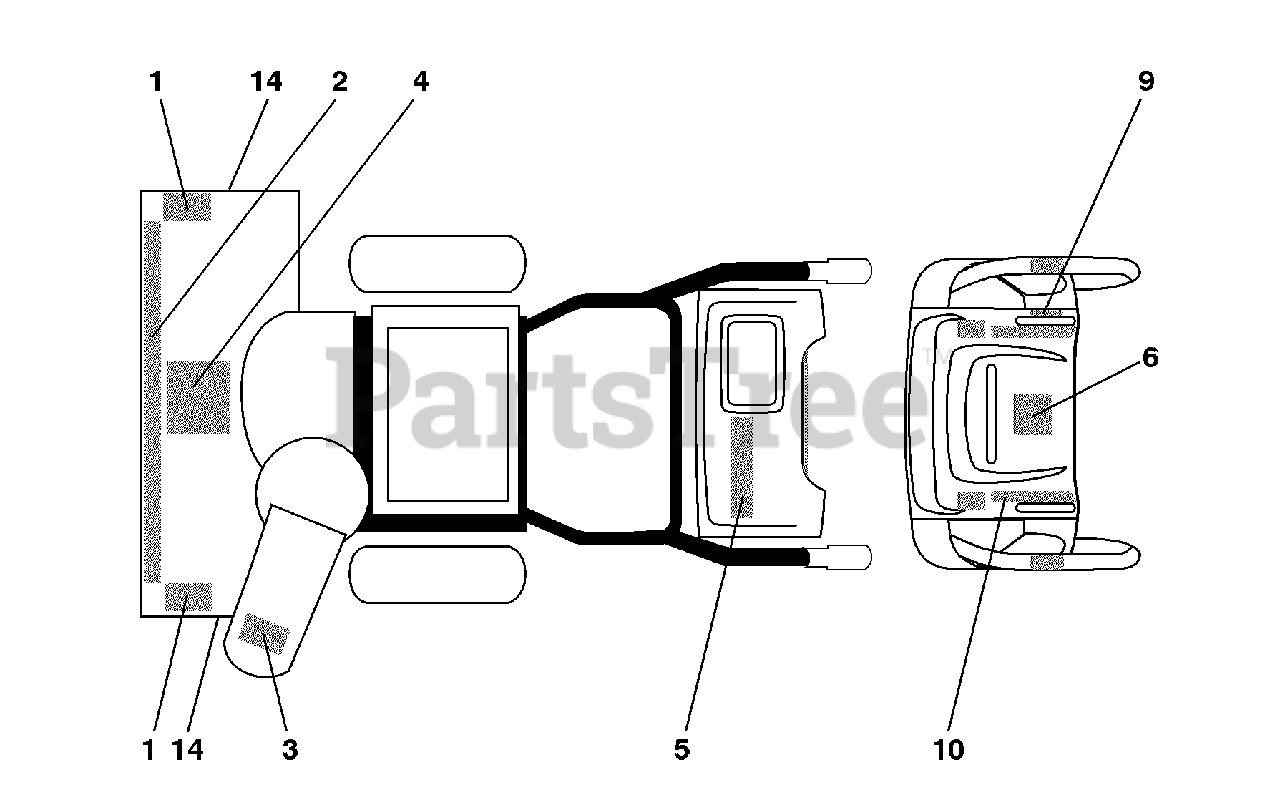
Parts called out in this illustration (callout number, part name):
1	Decal, Danger
2	Decal, Husqvarna
3	Decal, Danger, Defl ector
4	Decal, Danger
5	Decal, Husqvarna, 1330SBE-OV
6	Decal, Instruction
9	Decal, Speed Control
10	Decal, Remote Defl ector
11	Decal, LH Trigger
12	Decal, RH Trigger
14	Decal, Husqvarna, Crown
